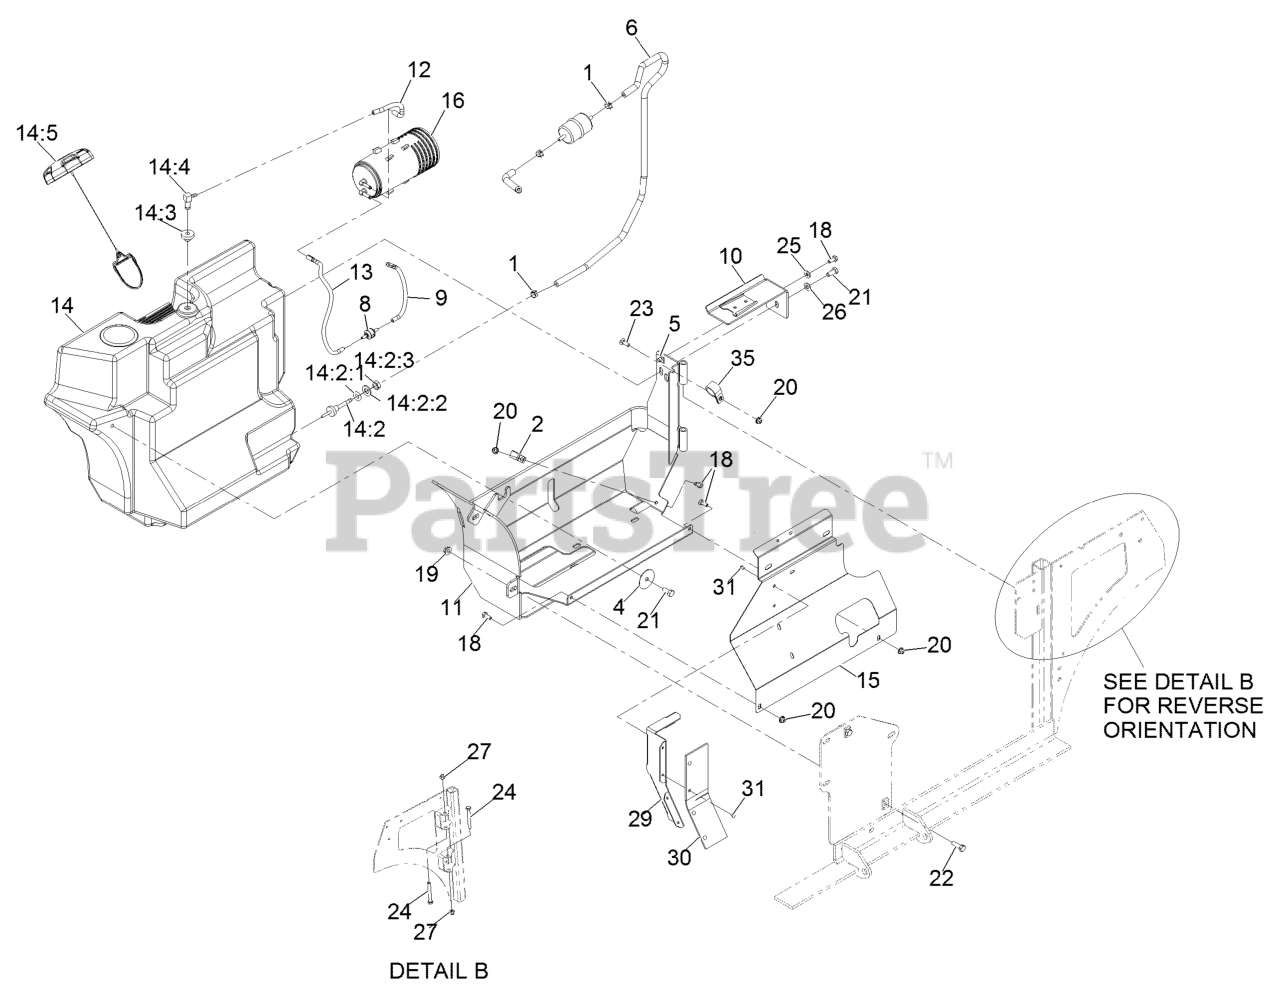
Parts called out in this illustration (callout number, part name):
1	CLAMP-HOSE
2	CLIP-LOOM
5	Nut-Retainer-Panel 1/4-20
6	HOSE-FUEL
9	HOSE-VENT, FORMED
10	CANISTER BRACKET ASM
11	TANK FRAME ASM
12	HOSE-VENT, FORMED
13	HOSE-VENT, FORMED
14	FUEL TANK ASM
14:2	FITTING-FUEL, BULKHEAD
14:2:1	O-RING,BULKHEAD FITTING
14:2:2	WASHER-FLAT
14:2:3	NUT-JAM
14:3	BUSHING
15	PANEL-TANK SHIELD
16	CANISTER-CARBON, 800CC
18	SCREW-HH
21	SCREW-HH
22	SCREW-HH
23	BOLT-CARR
24	SCREW-CARR
25	WASHER-FLAT
26	WASHER-PLAIN
27	NUT-LOCK, NI
29	DEFLECTOR-AIR
30	FLAP-RUBBER
31	RIVET-POP
35	R-CLAMP
